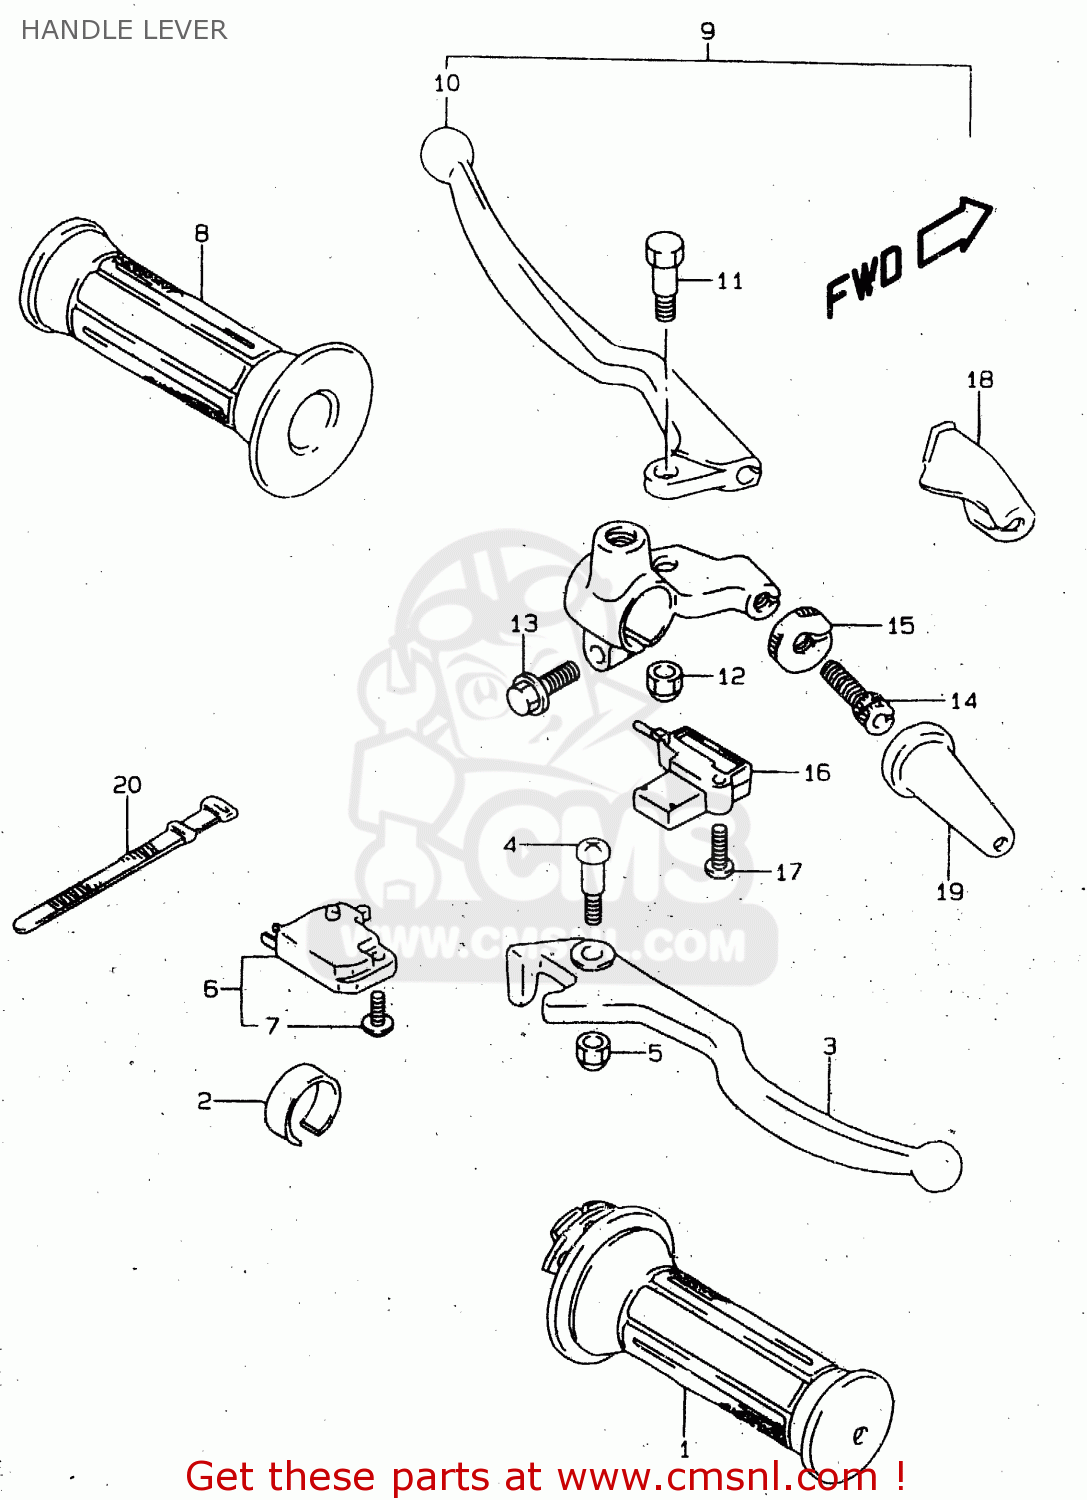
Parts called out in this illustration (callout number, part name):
1	GRIP,THROTTLE
2	SPACER,HANDLE SWITCH,R
3	LEVER,BRAKE
4	SCREW,BRAKE LEVER
5	NUT
6	SWITCH ASSEMBLY,STOP
7	SCREW
8	GRIP,L
9	LEVER ASSY,CLUTCH
10	LEVER,CLUTCH
11	BOLT,LEVER SET
12	NUT,LEVER PIVOT
13	SCREW
14	ADJUSTER,WIRE
15	NUT,LOCK
16	SWITCH,CLUTCH
17	SCREW
18	COVER,CLUTCH LEVER
19	BOOT,CLUTCH CABLE
20	CLAMP(L:120)
